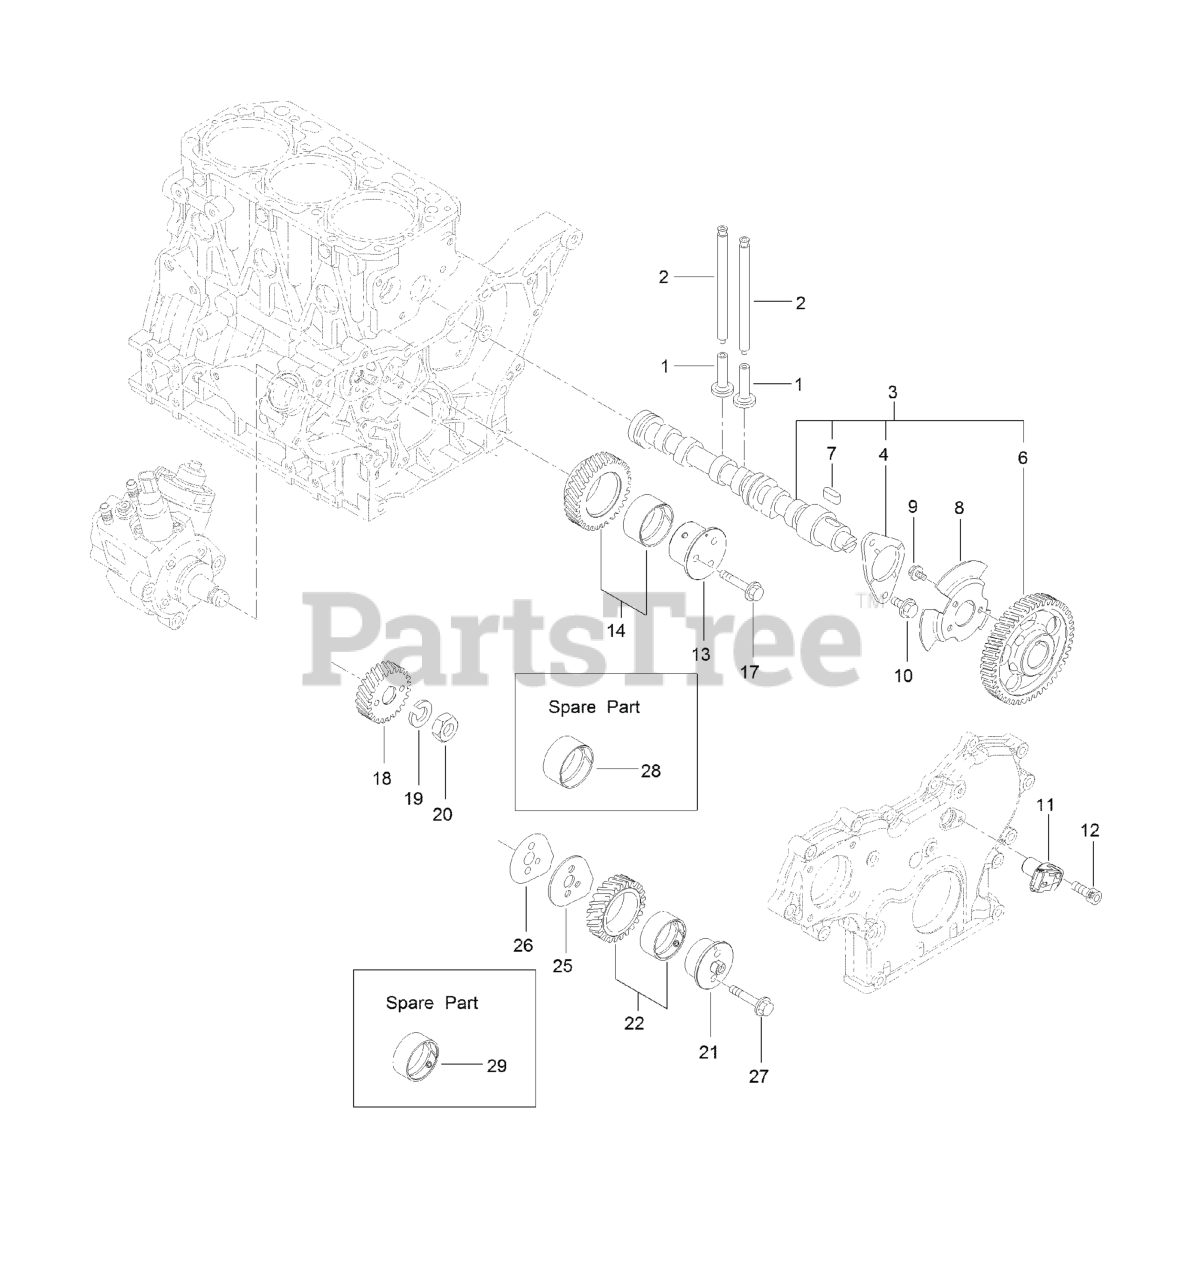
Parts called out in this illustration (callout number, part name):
2	ROD-PUSH
3	CAMSHAFT ASM
4	METAL-THRUST
6	Gear-Camshaft
8	PULSER-CAMSHAFT
11	SENSOR-REV, GEAR
13	Shaft-Idle, Gear A
14	IDLE GEAR A ASM
18	Gear-Pump, Supply
19	Washer-Spring
20	Nut-Lock
21	Shaft-Idle, Gear B
22	IDLE GEAR B ASM
25	Plate-Idle, Shaft
26	Gasket-Idle, Shaft B
28	BUSHING
29	BUSHING
